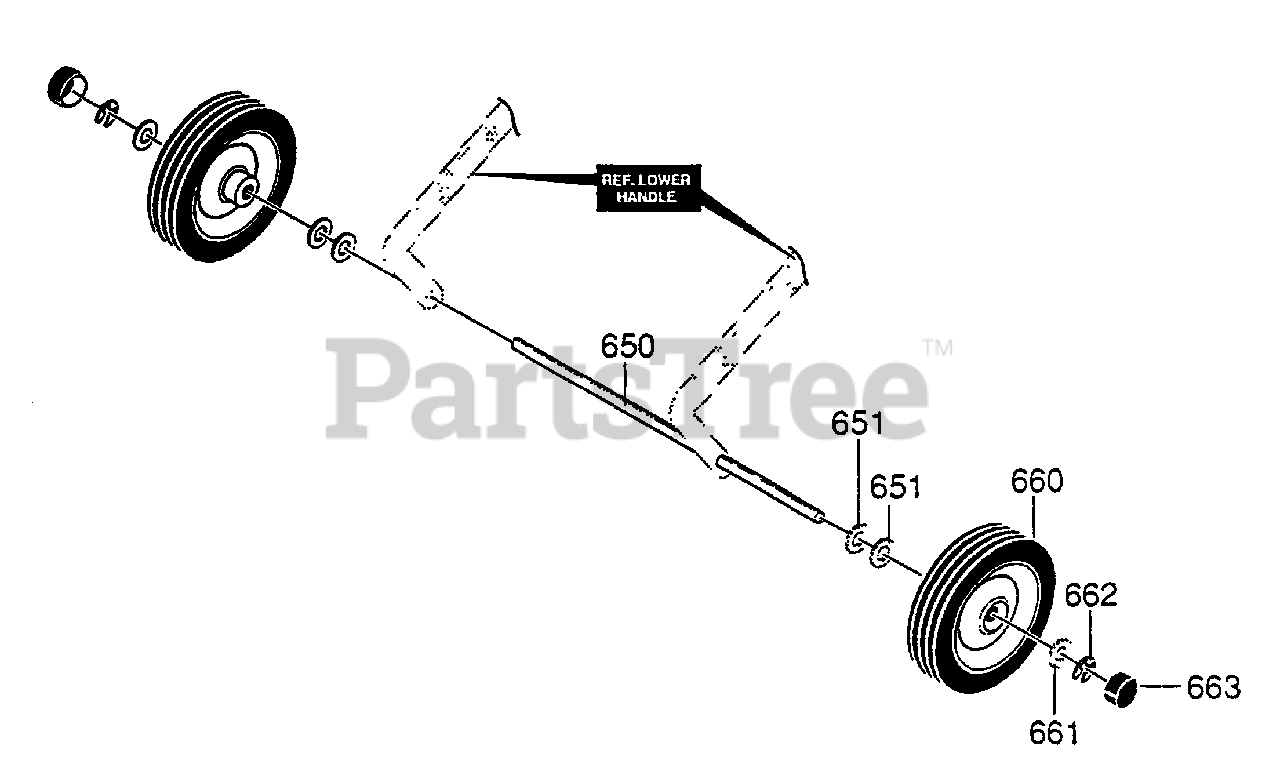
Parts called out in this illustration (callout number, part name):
650	AXLE, 7" SHAFT
651	FLATWASHER .391 X 1.00 X .125
660	TIRE & RIM 7 X 1.50
661	FLATWASHER .391 X 1.00 X .125
662	RING, RET E
663	HUB CAP 3/20
